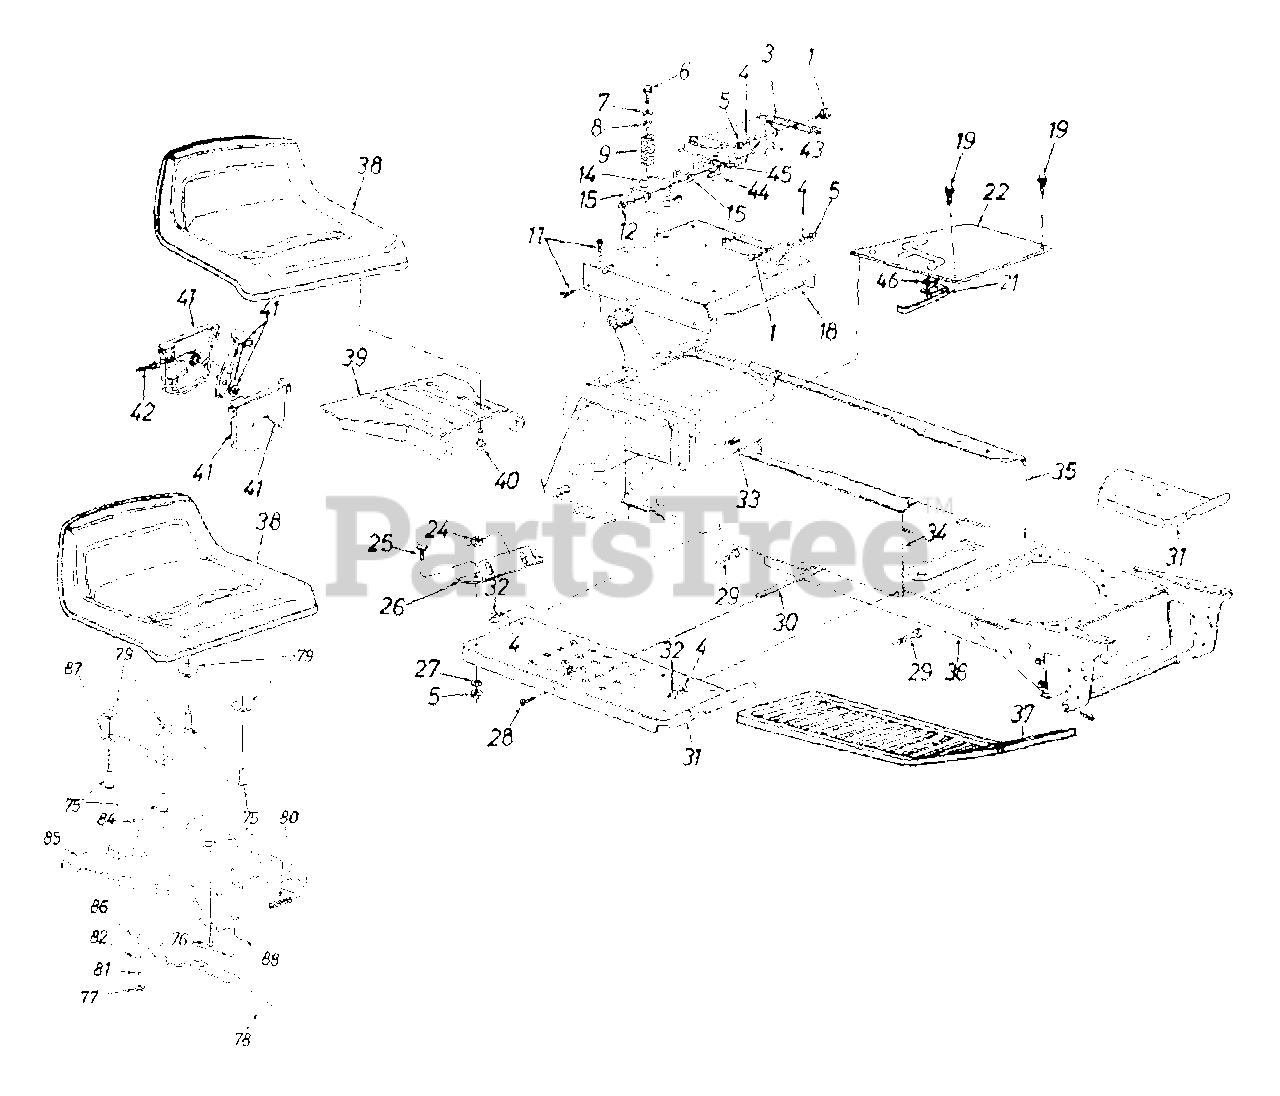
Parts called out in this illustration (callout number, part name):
1	Shld. Bolt .437" Dia. x .162"
3	Ext. Spring 5.31" Lg.
4	L-Wash. 5/16" I.D.
5	Hex Nut 5/16-1B Thd. (Gr. 5)
6	Hex Wash. Hd. Tap Scr. 5/16-18 x .7" Lg.
7	Fl-Wash. .344" I.D.
8	Bushing
9	Compression Spring
11	Hex Wash. Hd. AB-Tap Scr. 5/16 x .75"
12	Hx Wash. Hd. AB-Tap Scr. #8 x .5" Lg.
14	Spring Switch
15	Insulator Plate
18	Seat Plate
19	Truss Mach. B-Tap Scr.
21	Reverse Safety Switch
25	Hex Bolt 5/16-18 x .75" Lg.
28	Truss Mach. Scr. 5/16-18 x .75" Lg.
29	Rib Neck Bolt 5/16-24 x .75" Lg.
30	Running Board Rod
33	Speed Nut #102
38	Seat 8-7/8" High
40	Hex Tap Scr. 3/8-16 x .62" Lg.
41	Throttle Control Box Ass'y.
42	Throttle Control Wire 35" Lg.
43	Seat Lift Bracket
44	Seat Spring Switch
45	Insulator Boss Plate
46	Insulator Nut Plate
75	Hex Bolt 3/8-16 x 1" Lg.
76	Hex Washer B-Tap Scr. #10-16 x .38"
77	Hex Flanged L-Nut 1/4-20 Thd.
78	Seat Adjustable Grip
79	Spacer
80	Compression Spring 1.5" Lg.
81	Spring Wash. .265" I.D. x .56" O.D.
82	Fl-Wash. .344" I.D. x .62" O.D.
84	Shld. Bolt .34" x 1/4-20 Thd.
87	Seat Selector
88	Seat Stop
